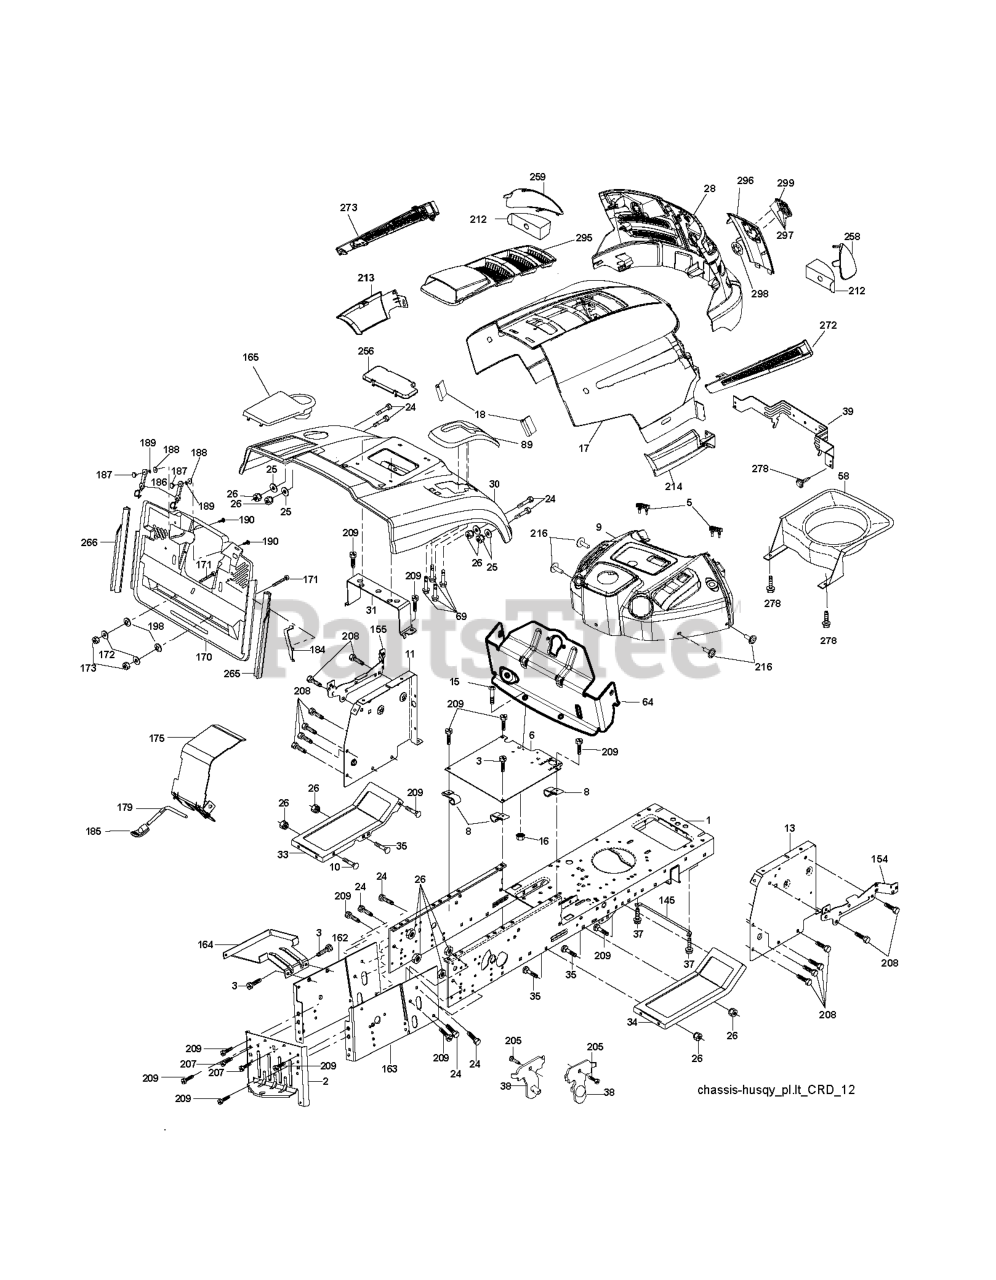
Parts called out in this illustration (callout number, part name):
2	DRAWBAR
3	SCREW 3/8-16X3/4
5	BUMPER DASH
6	PLATE
8	CLIP,INSULATOR
10	BOLT D
11	PANEL.DASH.LH.LTX
13	PANEL ASM, DASH RH
15	Screw, Machine, Truss Head 5/16-18 UNC x 3/4
16	NUT
17	HOOD
18	BUMPER.HOOD.TEX.HUSQVARNA
25	WASHER
26	NUT
28	RP GRILLE/LENS ASM.
30	CONSOLE.CRD.AUTO.GRY
31	BRACKET SUPPORT FENDER
33	FOOTREST PNT LH
34	FOOTREST PNT RH
37	Screw 5/16-18 x 1/2 Hex, Self Tapping 5/16-18 x 1/2
38	BRACKET ASM PIVOT MOWER REAR
39	BRACKET PIVOT
69	SCREW.HI-LO.CONSOLE
145	ROD.PIVOT.HOOD
162	BRACKET
163	BRACKET EXTEN CHASSIS RH CRD
165	RP.COVER.BATTERY.CRD.GREY
172	WASHER
175	DOOR TRAP
179	ROD PIVOT FBI
184	BRACKET.ACTUATOR.BAGGER.SRD
186	LATCH ASSY
187	WELDNUT
189	LOCKWASHER #10
190	SCREW
207	SCREW, 5/16-18 X 1/2
208	SCREW 3/8-16X1/2
209	SCREW, 3/8-16X3/4
212	INSERT REFLECTIVE
213	SKIRT SIDE LH
214	SKIRT SIDE RH
216	SCREW HEXWSHR 1/4-20X3/4
256	COVER FENDER CRD
258	LENS.HUSQVARNA LT.RH
259	LENS.HUSQVARNA LT.LH
265	SEALING
266	SEALING
272	VENT SIDE HOOD RH
273	VENT SIDE HOOD LH
278	SCREW
295	VENT TOP HOOD
296	TRIM
297	CLIP.RETAINER.TINNER.
298	NUT PUSH M
299	RP LOGO
